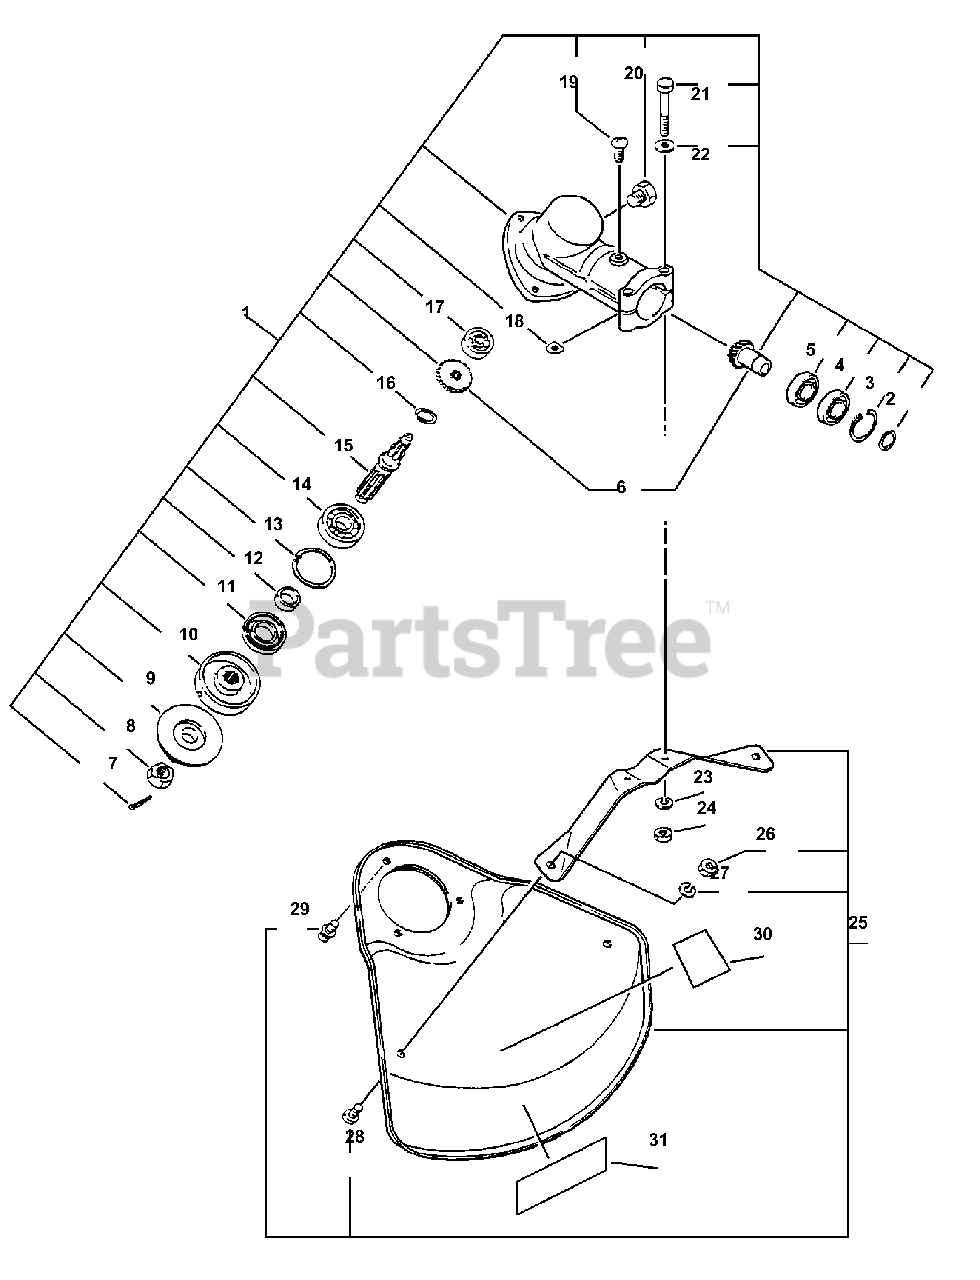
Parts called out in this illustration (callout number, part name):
1	GEAR CASE ASSY
2	RING, RETAINING - 10
3	RING, RETAINING - 22
4	BEARING, BALL - 6900Z
5	BEARING, BALL - 6900
6	GEAR SET - BEVEL
7	PIN, SPLIT - 2X22
8	NUT - 10 -- LEFT HAND
9	ADAPTOR, BLADE - LOWER
10	ADAPTOR, BLADE - UPPER
11	SEAL, OIL
12	SPACER
13	RING, RETAINING - 32
14	BEARING, BALL - 6201
15	GEAR - SHAFT
16	RING, RETAINING - 12
17	BEARING, BALL - 609
18	SHIM
19	SCREW - 5X10
20	BOLT - 8X8
21	BOLT - 5X35
22	WASHER - 5
23	LOCKWASHER - 5
24	NUT - 5
25	DEBRIS SHIELD KIT - METAL
26	NUT - 5
27	LOCKWASHER - 5
28	SCREW - 5X8
29	SCREW - 5X10
30	LABEL - CAUTION
31	LABEL - ECHO
